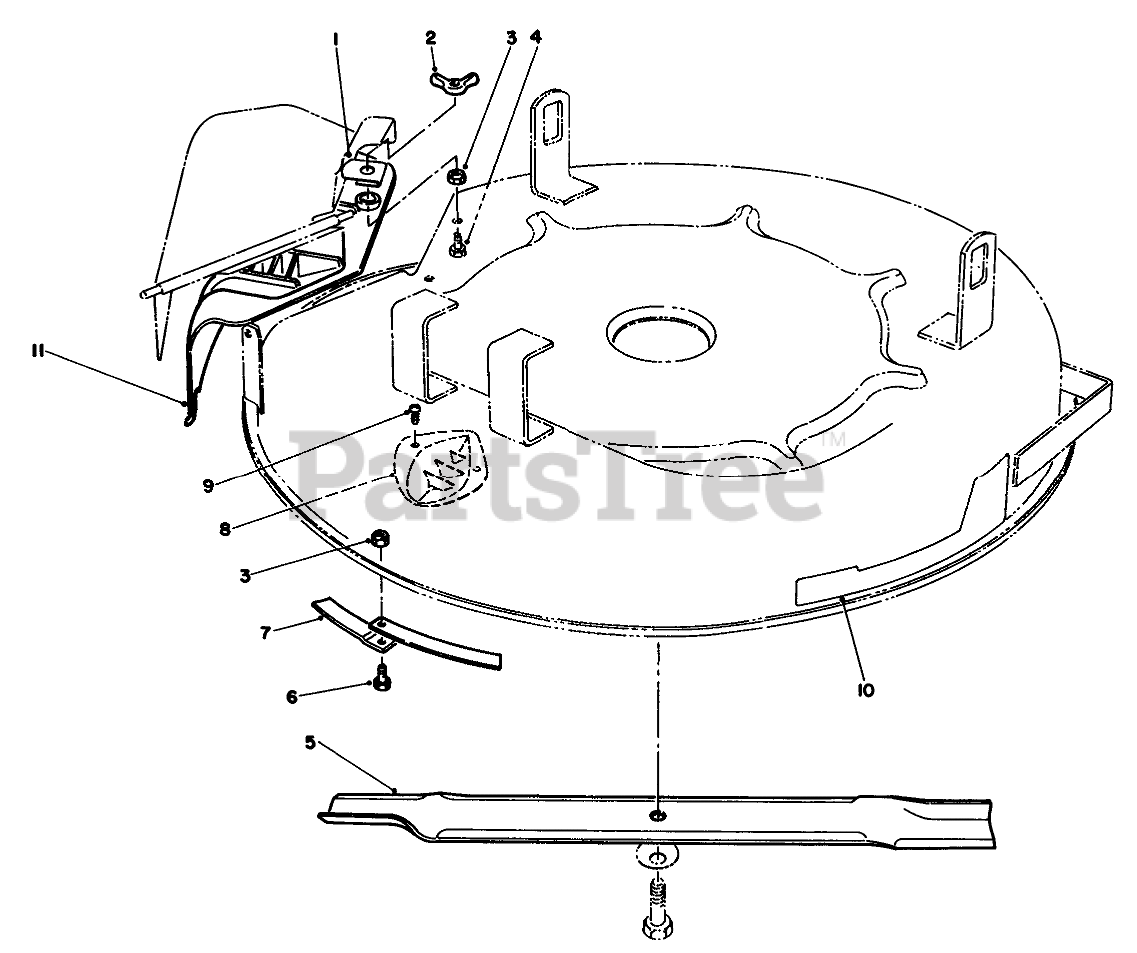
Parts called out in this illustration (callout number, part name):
2	NUT-WING SPECL
3	NUT-LOCK, NI
4	SCREW-HHF
5	Blade
6	SCREW-HH
7	Ring-Deck
8	KICKER
9	#8 X .625" PHILPS PAN H
10	DECAL - RECYCLER
11	COVER- 25" (W/KICKER)
